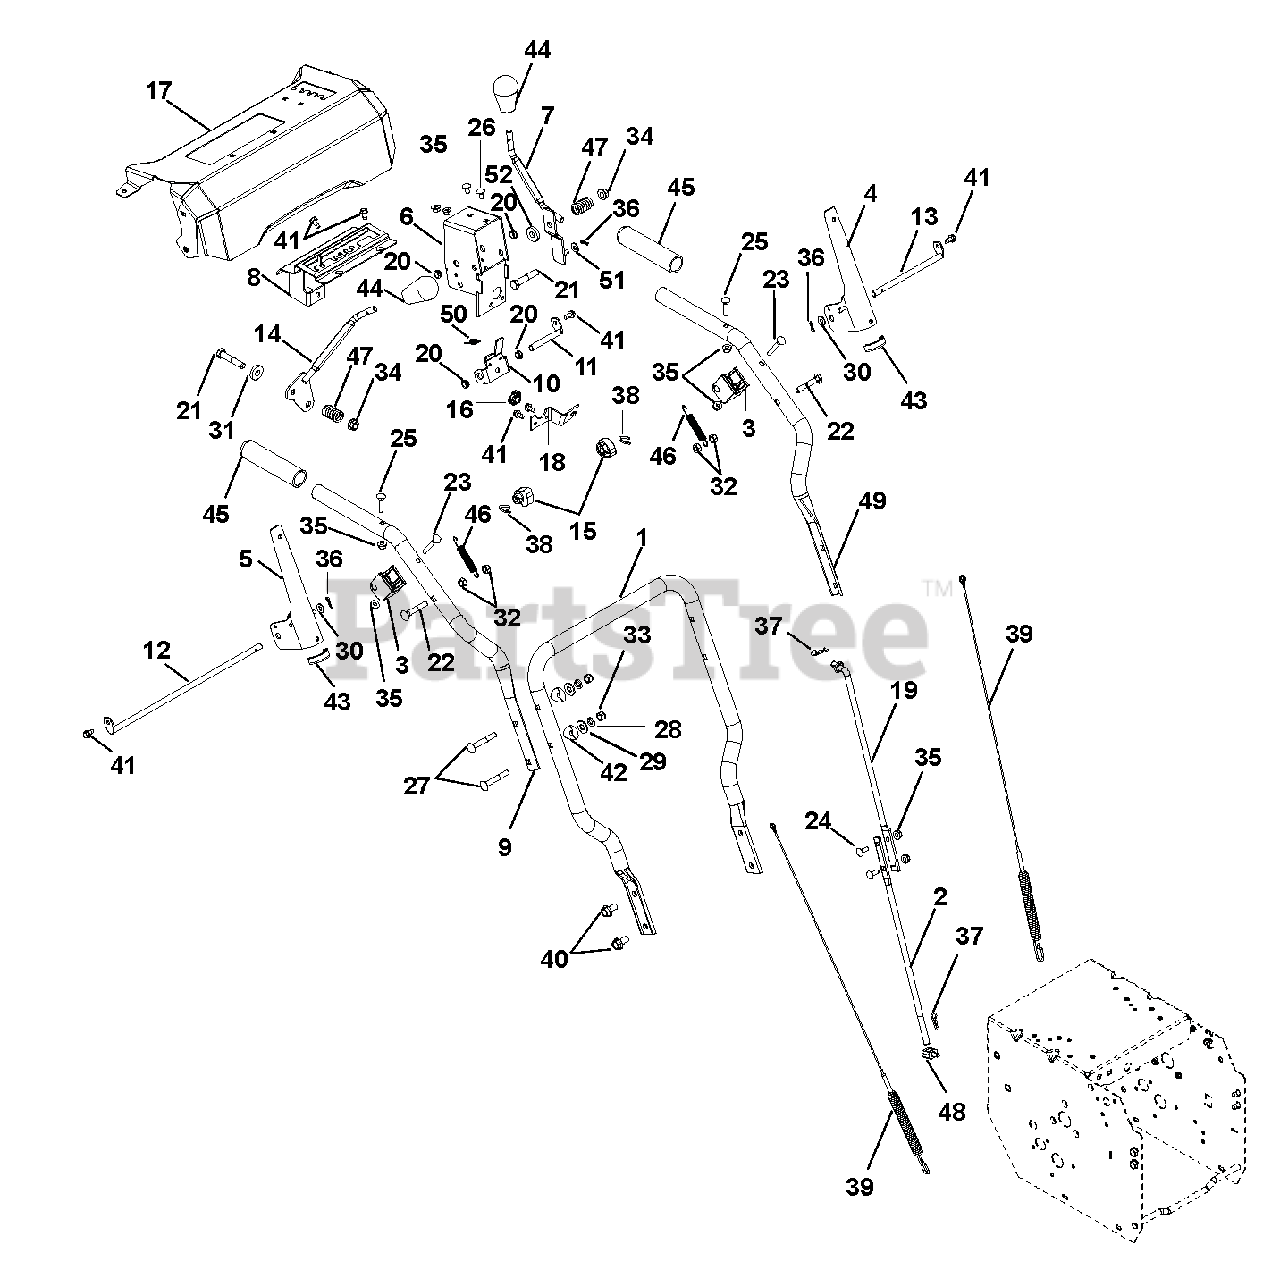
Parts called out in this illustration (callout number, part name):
1	HANDLEBAR, LOWER (COMPACT)
2	ROD, SHIFT - LOWER
3	BLOCK, CLUTCH PADDLE
4	LEVER, CLUTCH-LH
5	LEVER, CLUTCH-RH
6	WELDMENT, BRACKET INTERLOCK
7	WELDMENT, CONTROL LEVER (DEFL)
8	WELDMENT, DETENT PLATE-COMPACT
9	HANDLEBAR, UPPER - RH
10	BRACKET, INTERLOCK ARM
11	ROD, PIVOT - INTERLOCK
12	ROD, PADDLE MOUNT - LONG
13	ROD, PADDLE MOUNT - SHORT
14	LEVER, CONTROL-SHIFT(WELDMENT)
15	CAM, INTERLOCK
16	CRANK BUSHING, NYLON CHUTE BK
17	CONTROL PANEL W/DECAL, SNO-TEK
17	CTRL PANEL W/DECAL,SNO-TEK REM
18	ANCHOR, DEFLECTOR CABLE
19	ROD, SHIFT - UPPER
20	BUSHING, POLYLINER-.38 SNAPIN
21	@BLT-HEX .38-16X2.00 GR5 YWZC
22	BLT-RDHDXLSQNK .31-18X2.0 G5YZ
23	BLT-RDHDXLSQNK .25-20X2.0 G5YZ
24	@BLT-RDHDSQNK .25-20X.75 G5YZ
25	BLT-RDHDXLSQNK.25-20X1.25 G5ZC
26	@BLT-RDHDSQNK .25-20X.50 G5YZ
27	@BLT-RDHDSQNK .31-18X2.25 G5YZ
28	WSHR-LK .312X.097 HVY YWZC
29	@WSHR-FL-STL.38X.875X.083 YWZC
30	@WSHR-FL-STL.281X.62X.065 YWZC
31	WSHR-FL-STL .406X1.00X.188 YWZ
32	@NUT-LK-CTR .31-18 YWZC
33	@NUT-LK-NYL .312-18 YWZC
34	@NUT-LK-TOP-FLG .38-16 YWZC
35	@NUT-LK-TOP-FLG .25-20 YWZC
36	PIN-HAIR INT .06X.18X.77
37	PIN-HAIR INT .08X.18X1.18 YWZC
38	PIN, SPRING CLIP
39	CABLE, AUGER & UPPER TRACTION
40	BLT-SERHFWH .38-16X.75 YWZC
41	SCR-TAP .25-20X.50 HWH TR YWZ
42	SPACER, HANDLEBAR
43	EDGING, CLUTCH PADDLE - 2.00"
44	KNOB,SOFT TEARDROP,PUSH-ON BLK
45	HANDLE GRIP
46	SPRING, EXTENSION
47	SG-COMP .125X.781X1.250
48	PIVOT,SHIFT ROD .375-16(TRUNN)
49	HANDLEBAR, UPPER - LH
50	SPRING-EXT .047X.438X1.45
51	BSHG-SLV .265X.500X.219
52	WSHR-FL-STL .380X1.50X.062 YWZ
